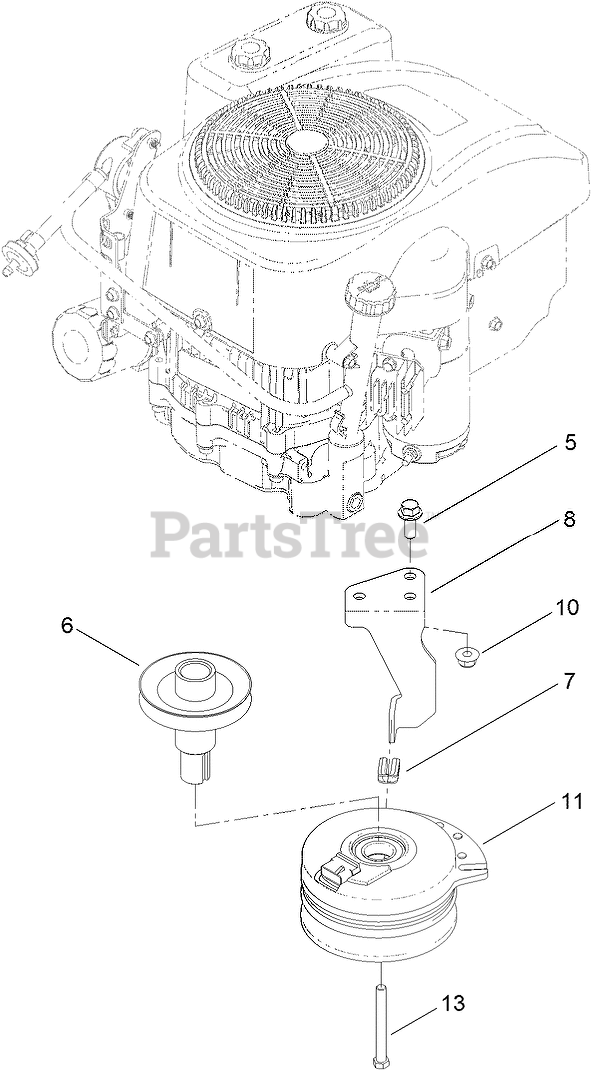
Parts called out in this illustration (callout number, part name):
5	SCREW-HHF
6	PULLEY-ENGINE
7	ISOLATOR-CLUTCH
8	STOP-CLUTCH
10	NUT-HF, NI
11	CLUTCH-ELECTRIC
13	SCREW-HH
